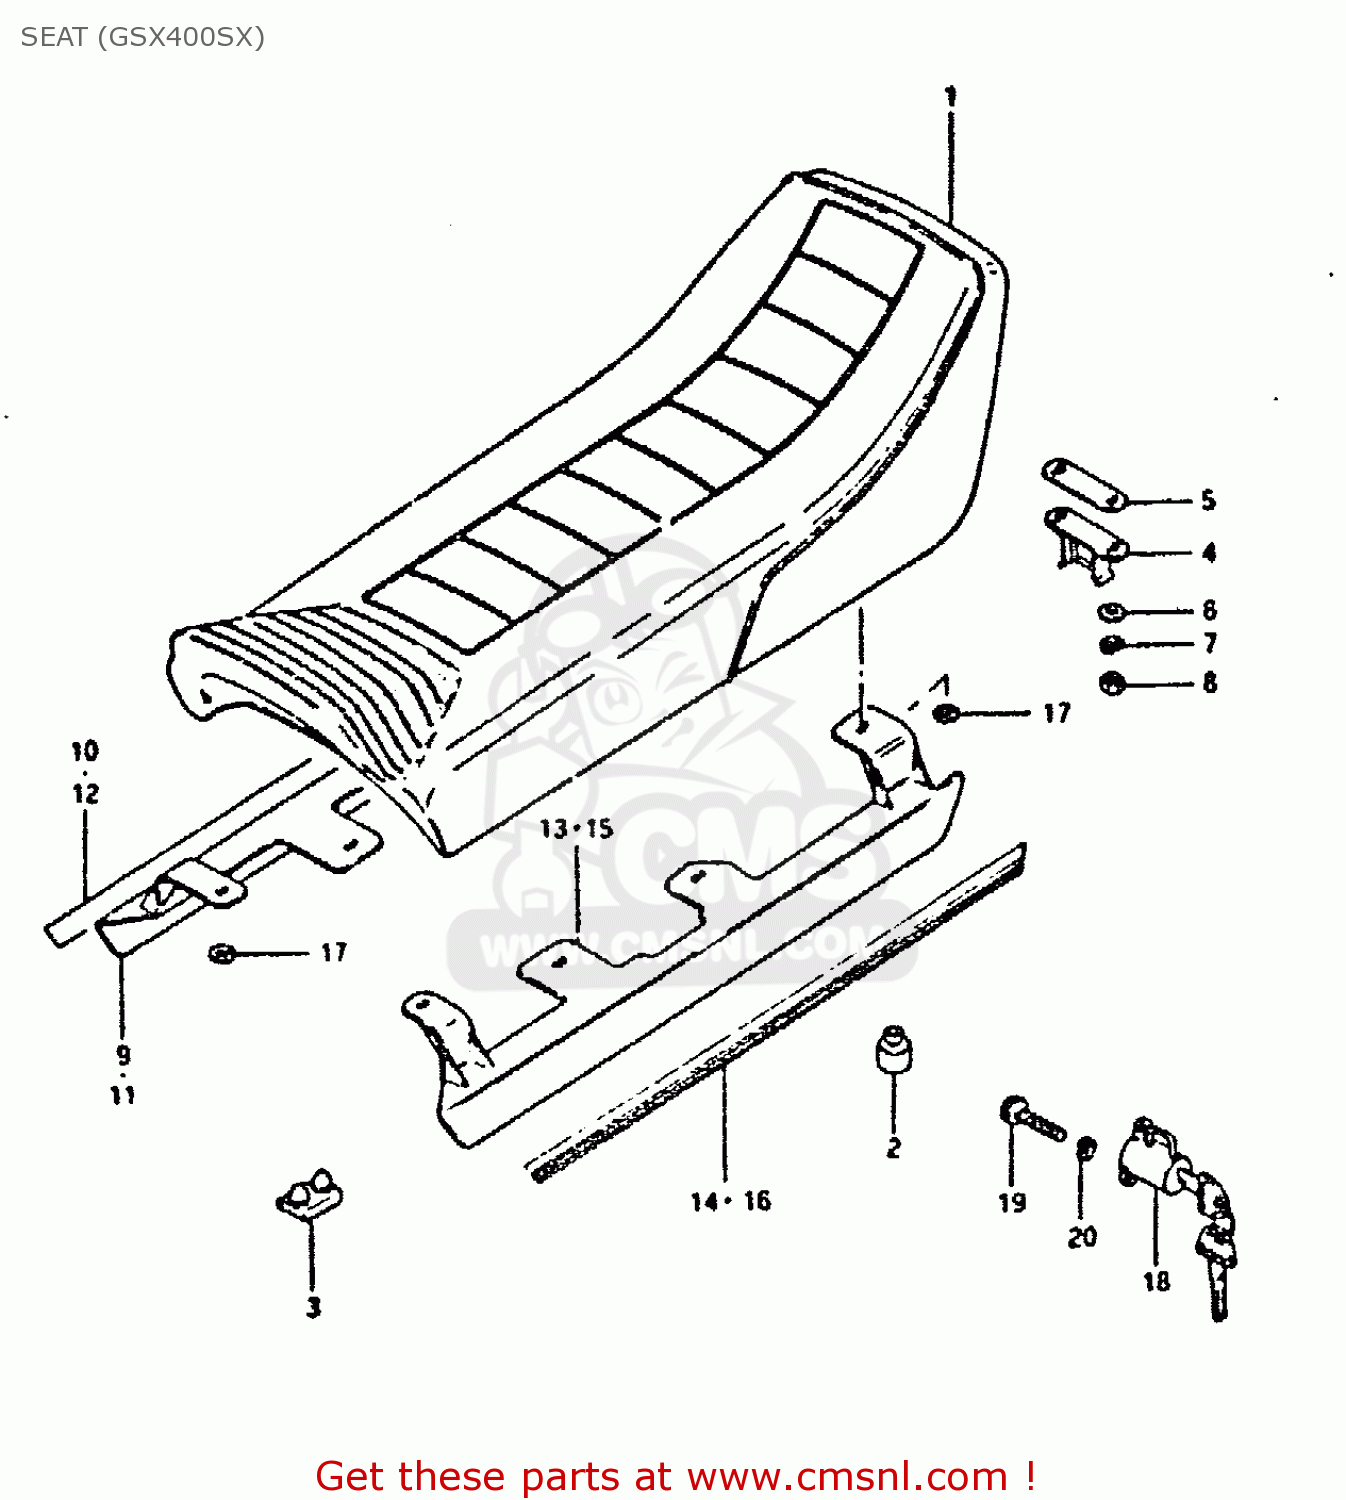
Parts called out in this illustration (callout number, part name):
1	SEAT ASSEMBLY
2	CUSHION
3	CUSHION
4	STRIKER,SEAT LOCK
5	SHIM,SEAT LOCK STRIKER
6	WASHER
7	LOCK WASHER
8	NUT 6MM
9	MOLDING,SEAT
10	TAPE, RH
11	MOULDING, SEAT RH (WHITE)
12	TAPE, RH
13	MOLDING,SEAT
14	TAPE, LH
15	MOULDING, SEAT LH (WHITE)
16	TAPE, LH
17	NUT
18	LOCK ASSEMBLY,HELMET
19	BOLT 6X11
20	LOCK WASHER
